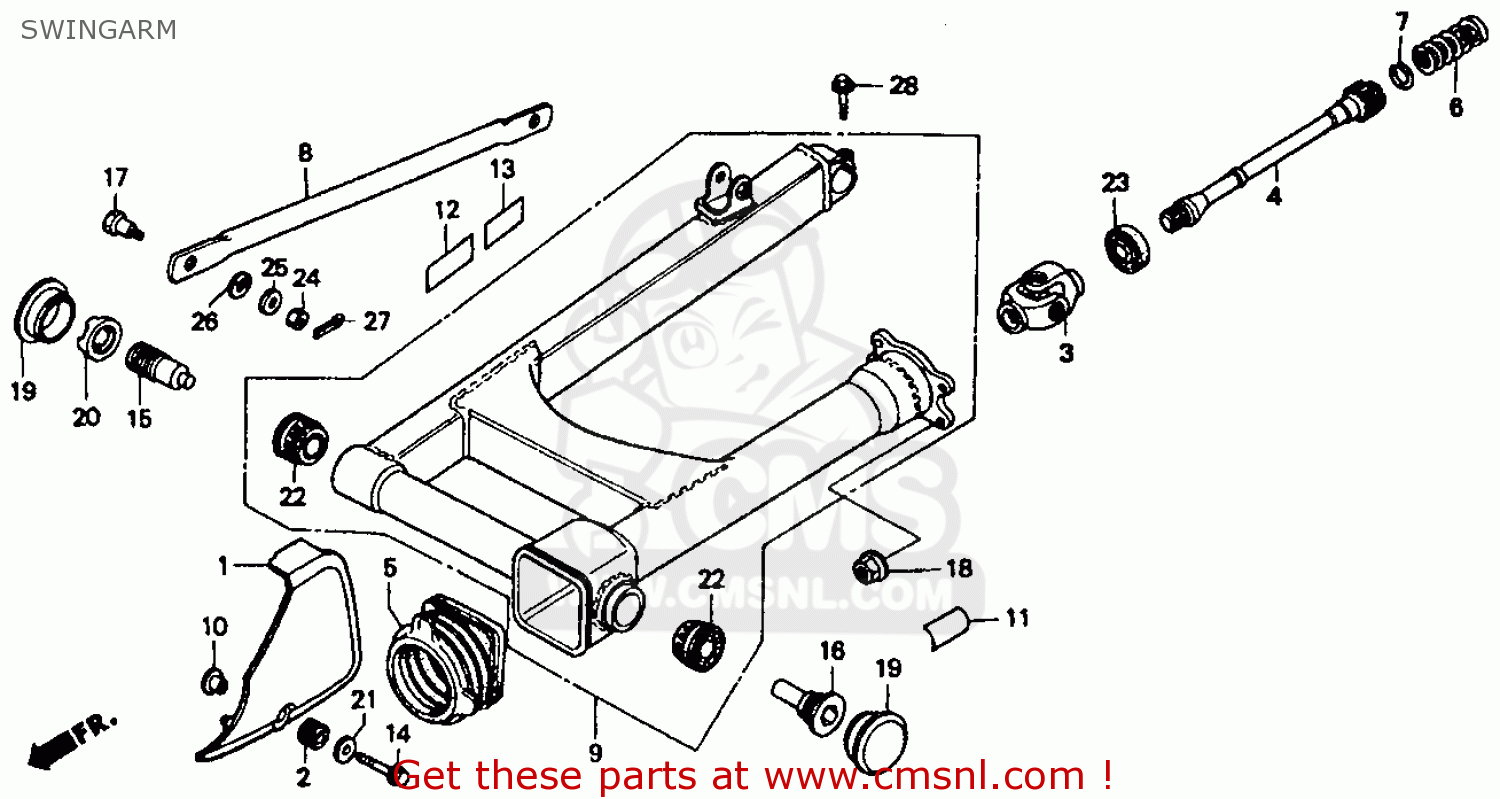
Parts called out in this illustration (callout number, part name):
3	JOINT COMP,YOKE
4	SHAFT,PROP.
5	BOOT,JOINT
6	SPRING,SHAFT
7	RING,STOPPER
8	ARM,RR.BRAKE STOP
9	ARM ASSY.*NH-1-Z*
11	MARK,TIRE CAUTION
13	MARK,ACCESS
14	BOLT,FLANGE,SOCKE
15	BOLT,R(RR.FORK) P
16	BOLT,L.RR.FORK
17	BOLT,STOPPER ARM
18	NUT,HEX.,10MM
19	CAP,R.LOCK NUT
20	NUT,RR.FORK PIVOT
21	WASH PLAIN 9MM
22	BRG,TAP.17X40X13.
23	OIL SEAL,27X43X7
25	WASHER,PLAIN,8MM
26	SPG-WASHER 10MM
27	PIN,COTTER 2.0X15
28	BOLT,FLANGE,8X32
